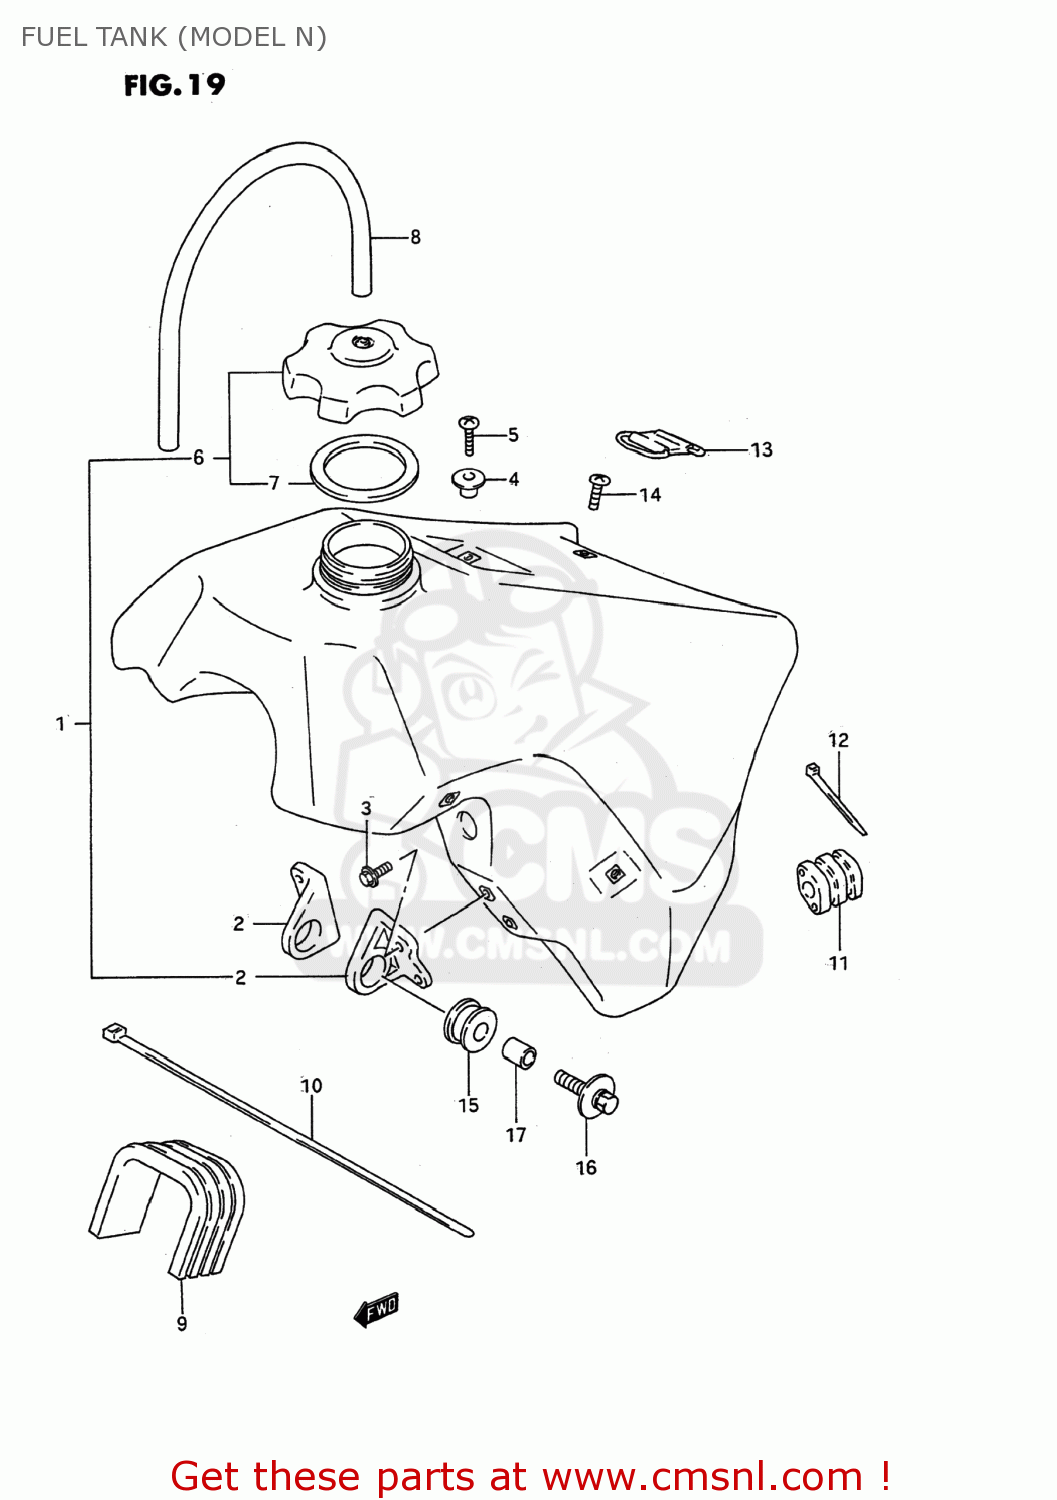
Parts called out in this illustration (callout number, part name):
1	TANK SET,FUEL
2	BRACKET,FUEL TANK FR
3	BOLT
4	HOOK,SEAT,FRONT
5	SCREW
6	CAP SET,FUEL TANK
7	GASKET,CAP (NAS)
8	HOSE
9	CUSHION,FUEL TANK
10	CLAMP(L:300)
11	CUSHION,FUEL TANK NO.2
12	CLAMP(L:145)
13	BAND,FUEL TANK RR
14	SCREW
15	CUSHION
16	BOLT(8X30)
17	SPACER (8.8X12X13.5)
